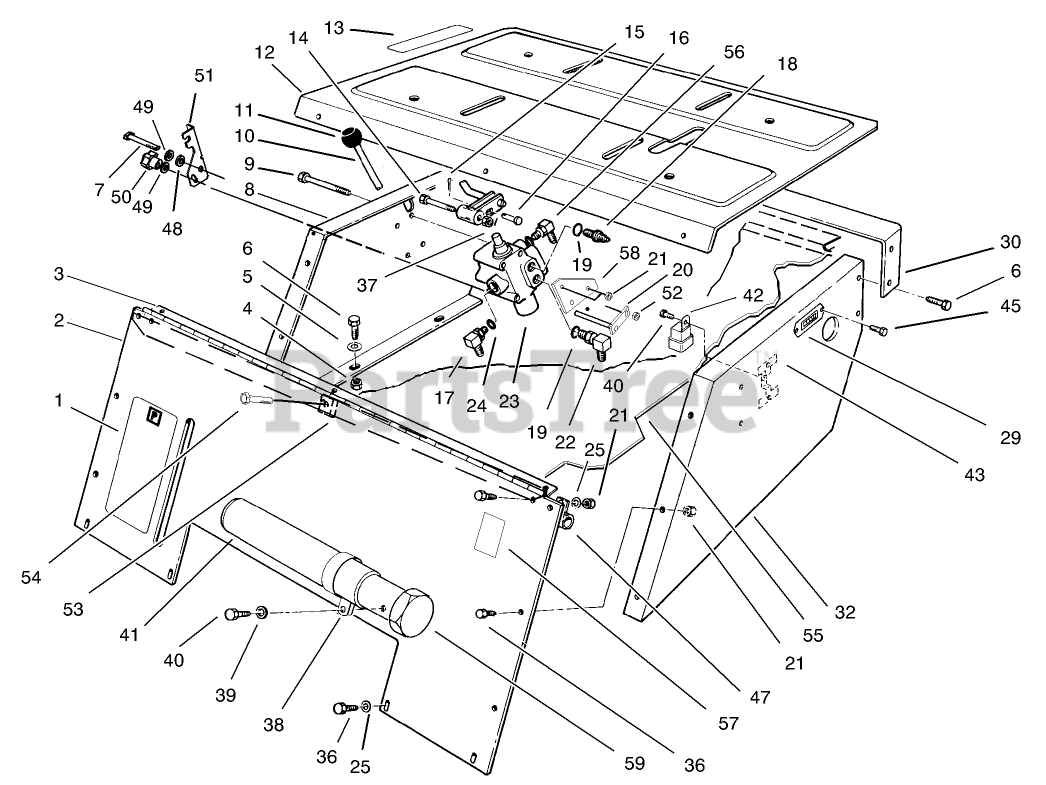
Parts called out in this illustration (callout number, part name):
1	DECAL - PARKING BRAKE
2	Support-Seat, Front
3	Hinge-Seat
4	NUT-LOCK, NI
5	WASHER-PLAIN
6	SCREW-HH
7	SCREW-HH
8	Support-Seat RH.
9	SCREW-HH
10	Lever-Valve
12	Plate-Seat
13	DECAL - LIFT CONTROL
14	BOLT-WHEEL
15	PIN-COTTER
16	PIN-CLEVIS
17	FITTING-HYD, 90 DEG
18	FITTING-STRAIGHT
19	O-RING
20	LEVER BRACKET
21	NUT-LOCK, NI
22	FITTING-ELBOW, 90
23	VALVE ASM
24	O-RING
25	WASHER-FLAT
29	HOURMETER
30	Support-Hood
32	Support-Seat L.H.
36	SCREW-HH
37	NUT-LOCK, NI
38	CLAMP-R
39	WASHER-FLAT
40	SCREW-HWH
41	TUBE-MANUAL
42	RELAY
43	Bracket
45	SCREW-HWH
48	SPACER - LATCH
49	WASHER-FLAT
50	KNOB-CHUTE
51	BRACKET - HYDRO LOCK
52	NUT-LOCK, NI
53	NUT-SPEED
54	SCREW-HH
55	Cover-Belt
56	FITTING-ELBOW, 90 DEG
57	DECAL-PROTECTION, EAR
58	LEVER BRACKET
59	CAP-HOUSING
